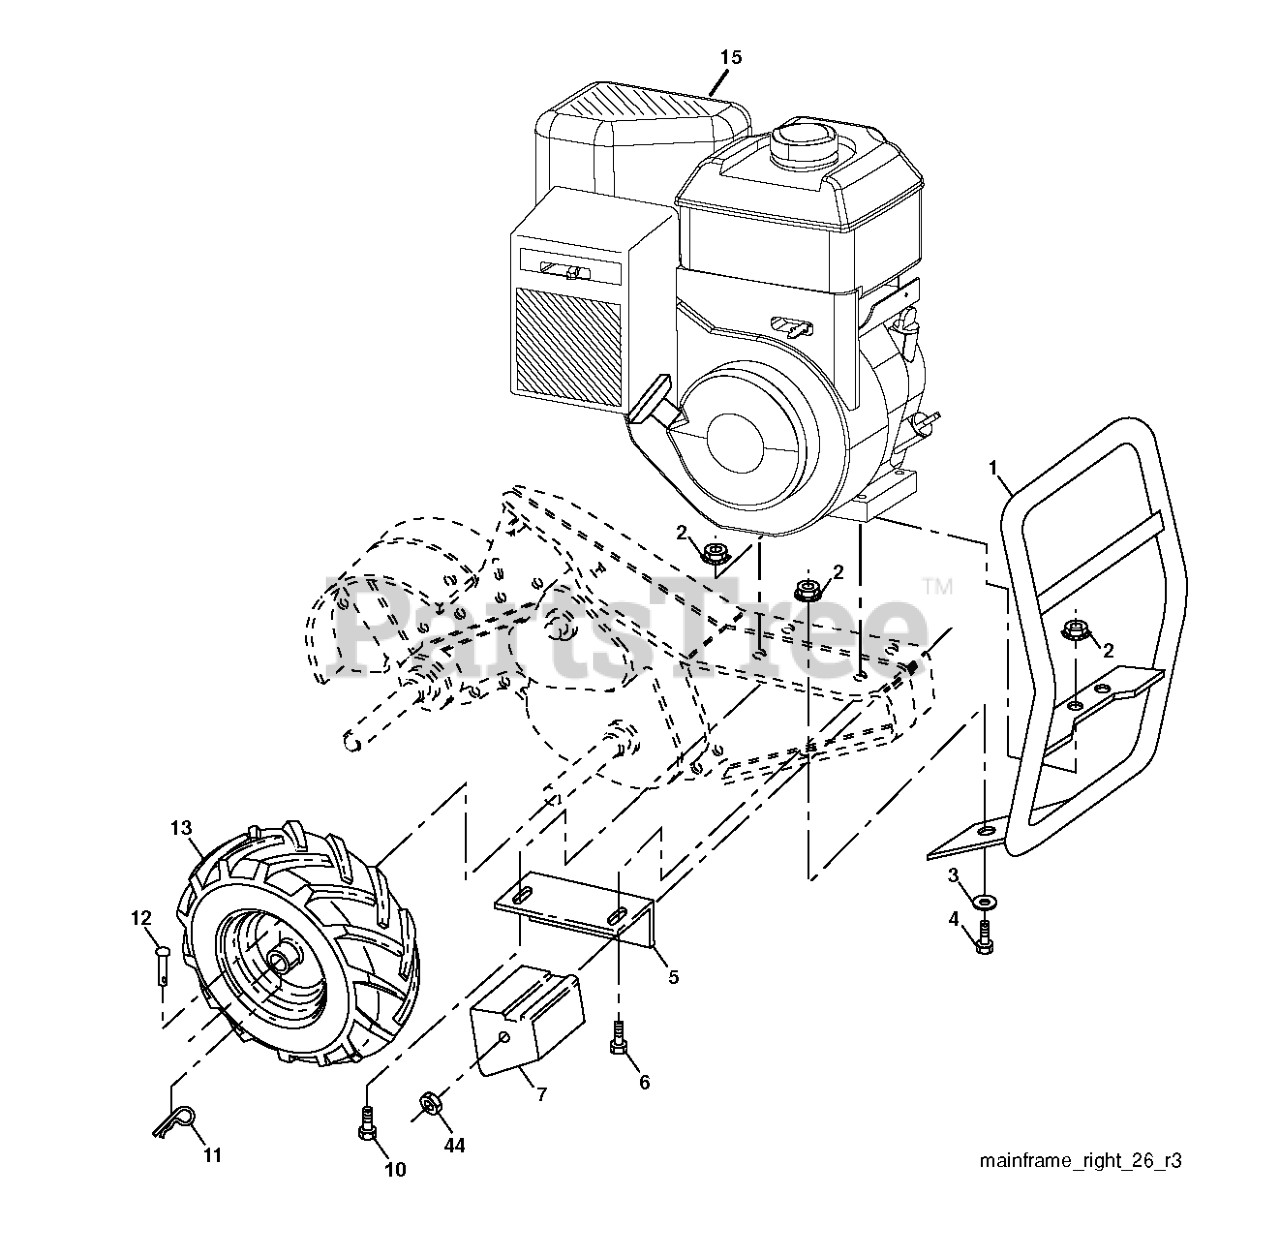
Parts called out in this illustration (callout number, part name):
1	RP.BUMPER.ASM.TILLER.
2	LOCKNUT-FLANGE 5/16-18
3	WASHER
4	BOLT
5	DNO BRACKET RH CRT
6	BOLT, HEX 5/16-18X1-3/4
7	COUNTERWEIGHT, RH
10	BOLT
11	RETAINER M
12	RIVET,DRILLED
13	TIRE.13X5-6.CHEVRON.TILLER
13	RIM.ASM.6".SILVER
13	VALVE STEM LT
15	Husqvarna TBD
